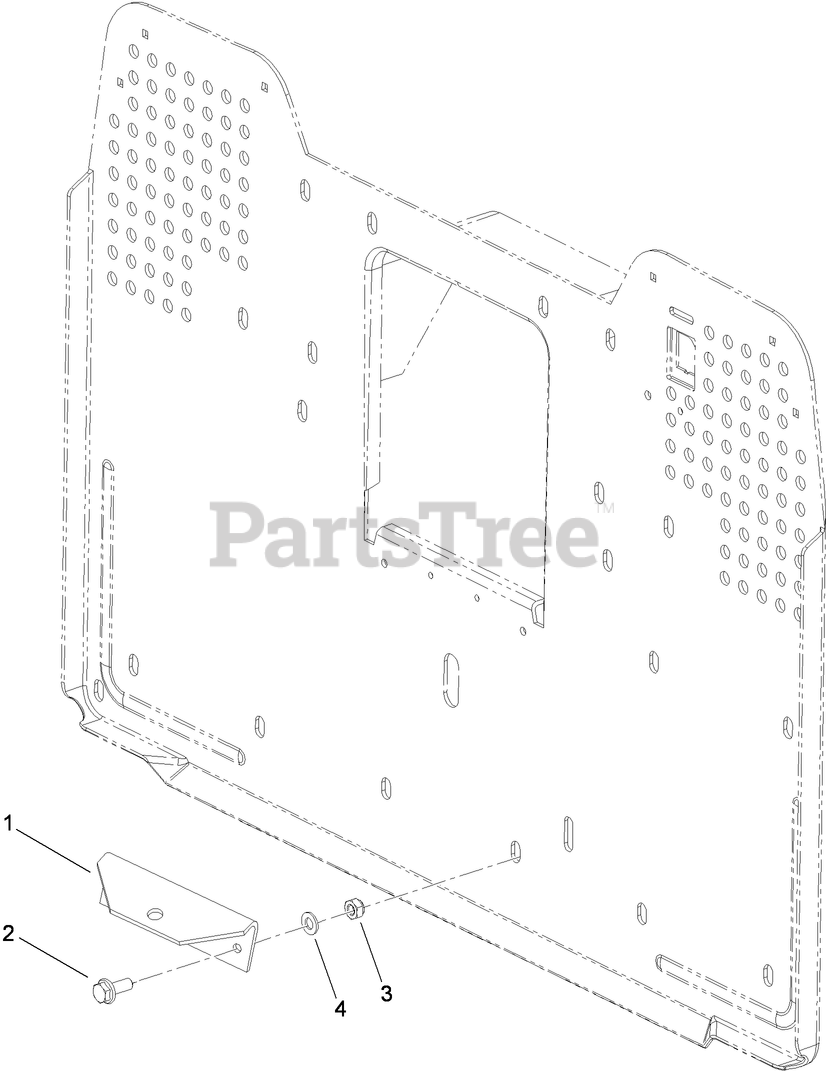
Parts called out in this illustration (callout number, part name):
1	HITCH-TOW
2	SCREW-HHF
3	WASHER-PLAIN
4	NUT-LOCK, NI
